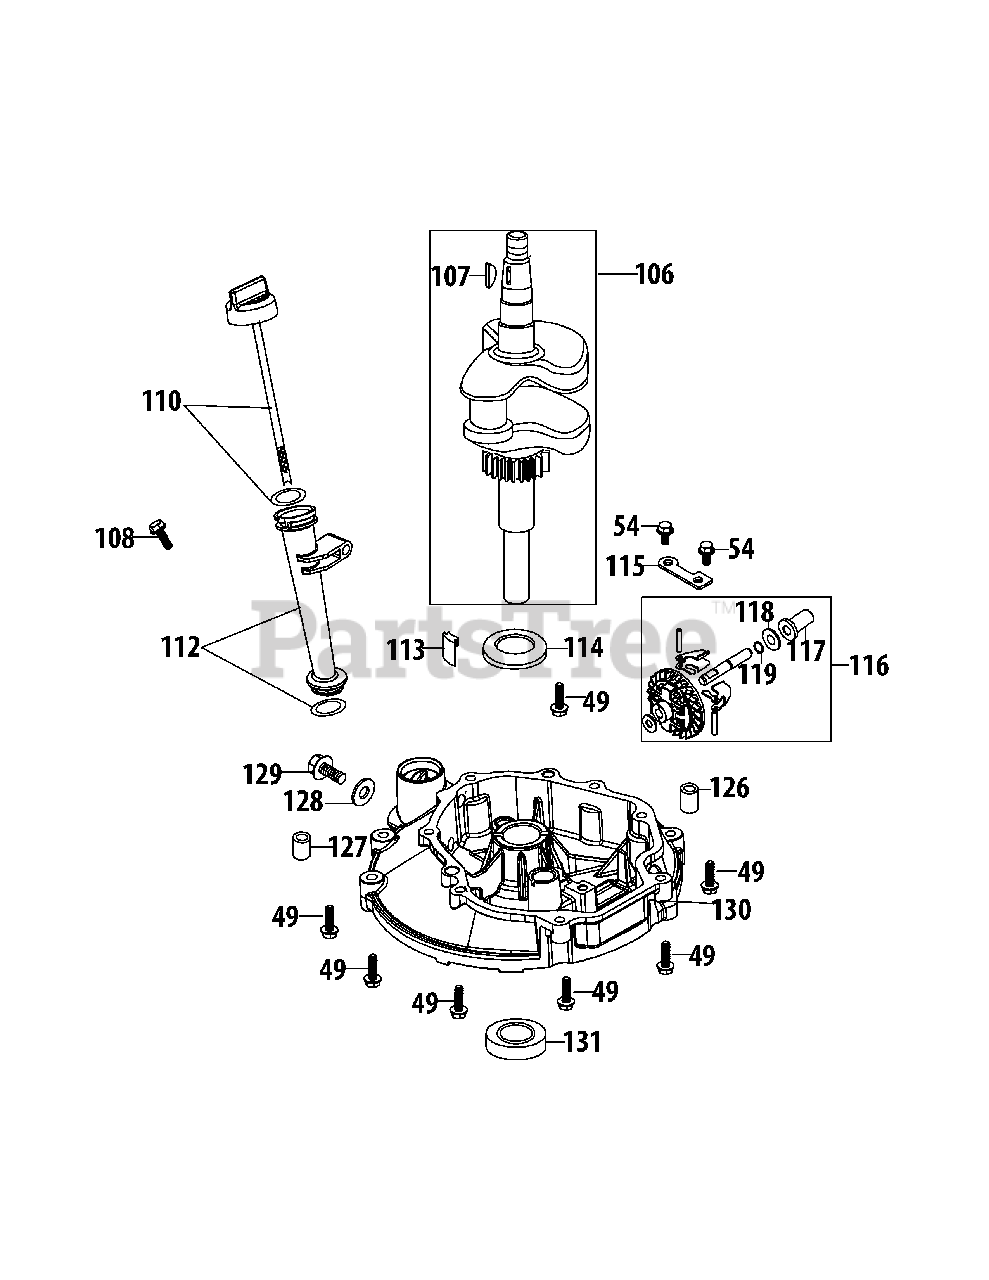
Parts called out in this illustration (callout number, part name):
49	Bolt M6X28 T/X/P Crankcase/Dp Stick
54	Bolt M6X14 Multi-Purpose
106	Crankshaft Assembly
107	Flywheel Key
108	Bolt M6X35 Af Base/Brake/Dipstick
110	Dipstick
112	Oil Fill Tube
113	Oil Return Seal
114	Crankshaft Thrust Washer
115	Governor Gear Mounting Plate
116	Governor Gear/Shaft Assembly
117	Governor Slide Cap
118	Governor Slide Cap Washer
119	Governor Shaft Stop Ring
126	Crankcase Cover Dowel Pin 07×14
127	Crankcase Cover Dowel Pin 09×14
128	Oil Drain Plug Washer
129	Oil Drain Plug
130	Crankcase Cover
131	Lower Crankshaft Seal
